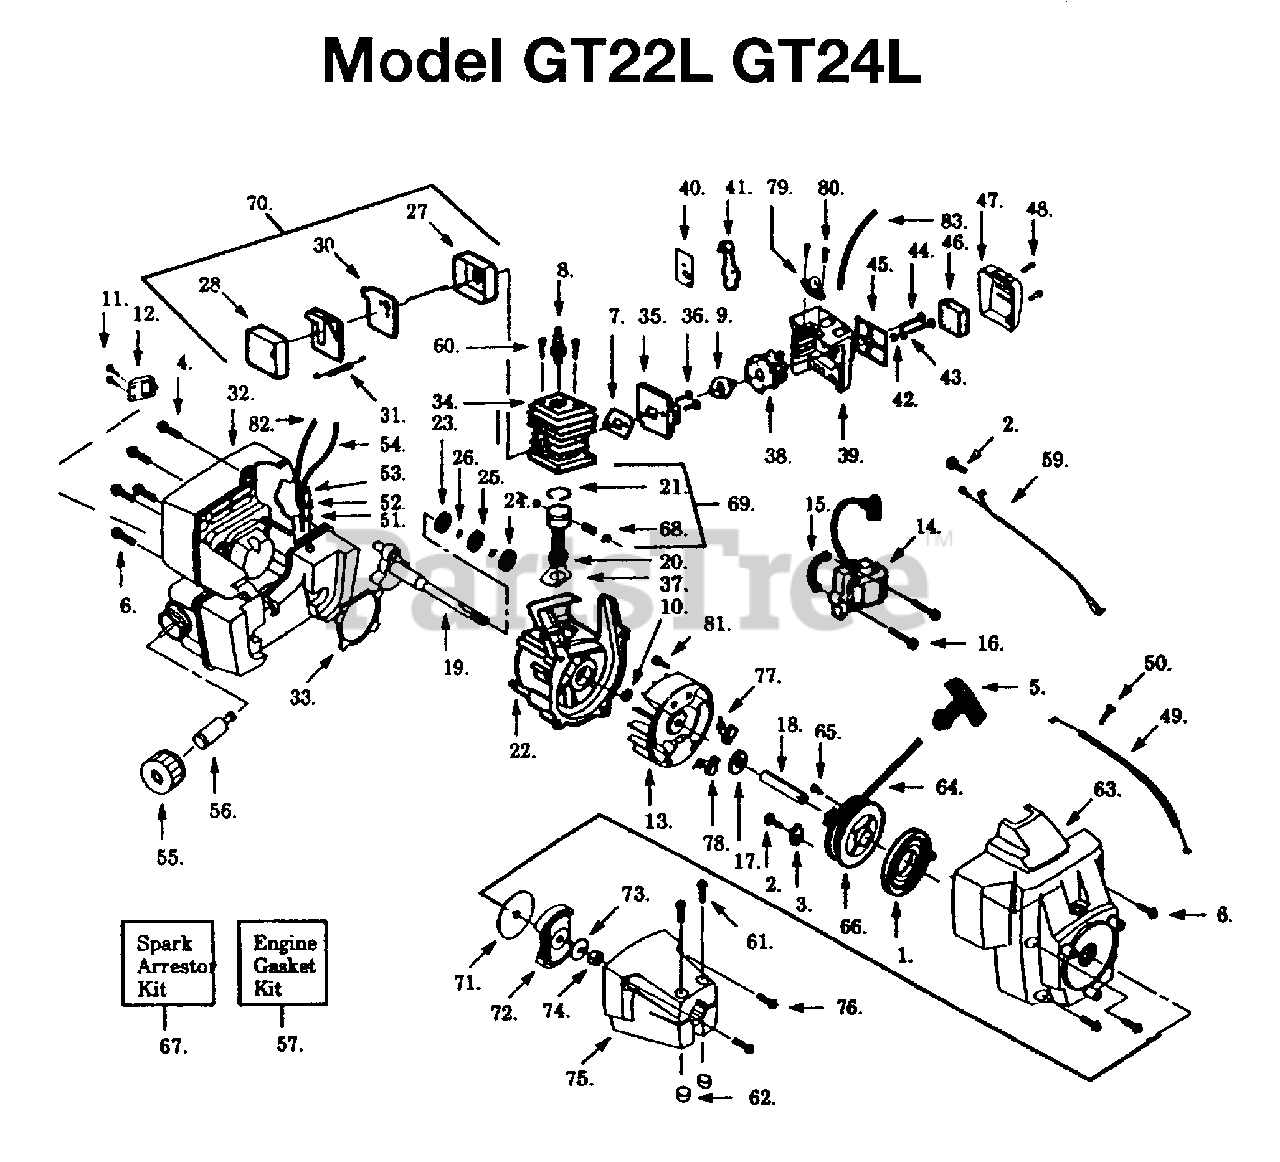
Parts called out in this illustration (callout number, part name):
1	SPRING-STARTER
2	SCREW 8-16 X 9/16 (PLAS
5	HANDLE-STARTER
6	SCREW-10-14 X 13/16 (PL
7	GASKET
8	SPARK PLUG CJ8 NLA
9	GASKET
11	SCREW-8-18 X 5/18(RECES
12	MUFFLER GUARD
13	FLYWHEEL
14	IGNITION MODULE
15	SPACER - IGNITION MODULE
17	WASHER FLAT
19	CRANKSHAFT
20	CONNECTING ROD ASSEMBLY
21	PISTON RING
22	CRANKCASE ASSY
23	BEARING
25	SEALING RING
26	RETAINING RING
27	MUFFLER BODY
28	MUFFLER COVER
30	MUFFLER BAFFLE - FIRST
31	MUFFLER SPRING
33	GASKET, CRANKCASE
35	CARB. ADAPTER
36	SCREW - CARB. ADAPTOR
37	GASKET - CYLINDER
38	CARBURETOR
40	CHOKE PLATE
41	CHOKE SHUTTER
43	CHOKE SPACER
45	FILTER PLATE
46	AIR FILTER FOAM
47	AIR FILTER COVER
48	SCREW - THROTTLE HOUSING
51	VALVE-CHECK (DUCKBILL)
55	CAP ASSY W/ RETAINER
56	FUEL PICK UP ASSY
59	LEAD WIRE ASSEMBLY
61	SCREW - PINCH CLAMP
62	LOCKNUT-HEX 10-24
66	STARTER PULLEY KIT
67	KIT-SPARK ARRESTOR (OLD STYLE)
68	WRIST PIN RET.
69	REPAIR KIT
71	FRICTION DISC,CLUTCH 36/41
72	CLUTCH ASSEMBLY KIT
73	WASHER-FLYWHEEL
76	SCREW-10-14 X 13/16 (PL
78	STARTER DOG SPRING
79	PRIMER BULB ASSEMBLY
82	FUEL LINE - PRIM/TNK
